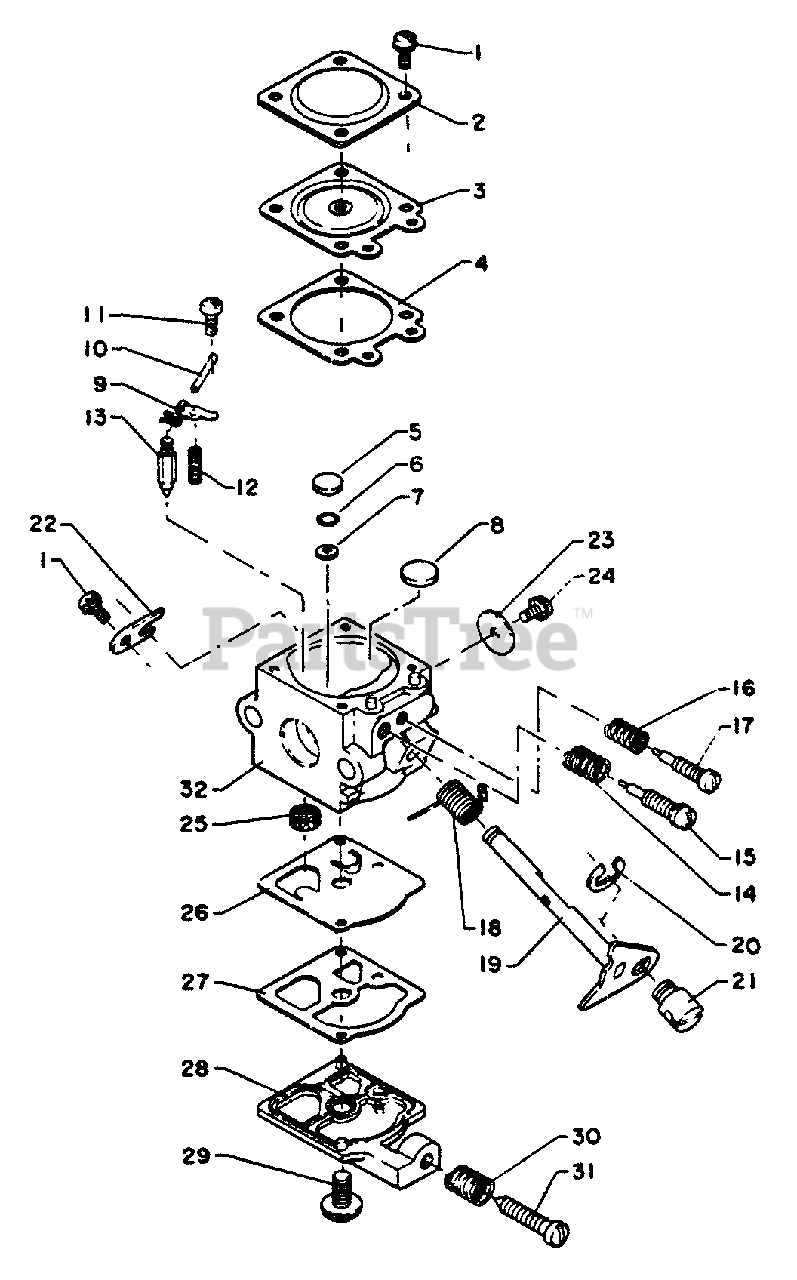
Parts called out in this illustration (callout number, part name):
1	SCREW
2	COVER, METERING
3	DIAPHRAGM, METERING
4	GASKET, METERING
5	PLUG, WELCH
6	RING, RETAINING
7	STRAINER
8	PLUG, WELCH
9	LEVER, METERING
10	PIN, METERING LEVER
11	SCREW, METERING LEVER PIN
12	SPRING, METERING LEVER
13	VALVE, INLET NEEDLE
14	SPRING, HIGH SPEED NEEDLE
15	NEEDLE - HIGH SPEED
16	SPRING
17	NEEDLE - LOW SPEED
18	SPRING, THROTTLE RETURN
19	SHAFT, THROTTLE
20	RING, RETAINING
22	CLIP, THROTTLE SHAFT
23	VALVE, THROTTLE
25	STRAINER
26	DIAPHRAGM, PUMP
27	GASKET, PURGE
28	COVER, PUMP
29	SCREW, PUMP COVER
30	SPRING, IDLE ADJUST
31	SCREW, IDLE ADJUST
32	BODY, CARBURETOR
